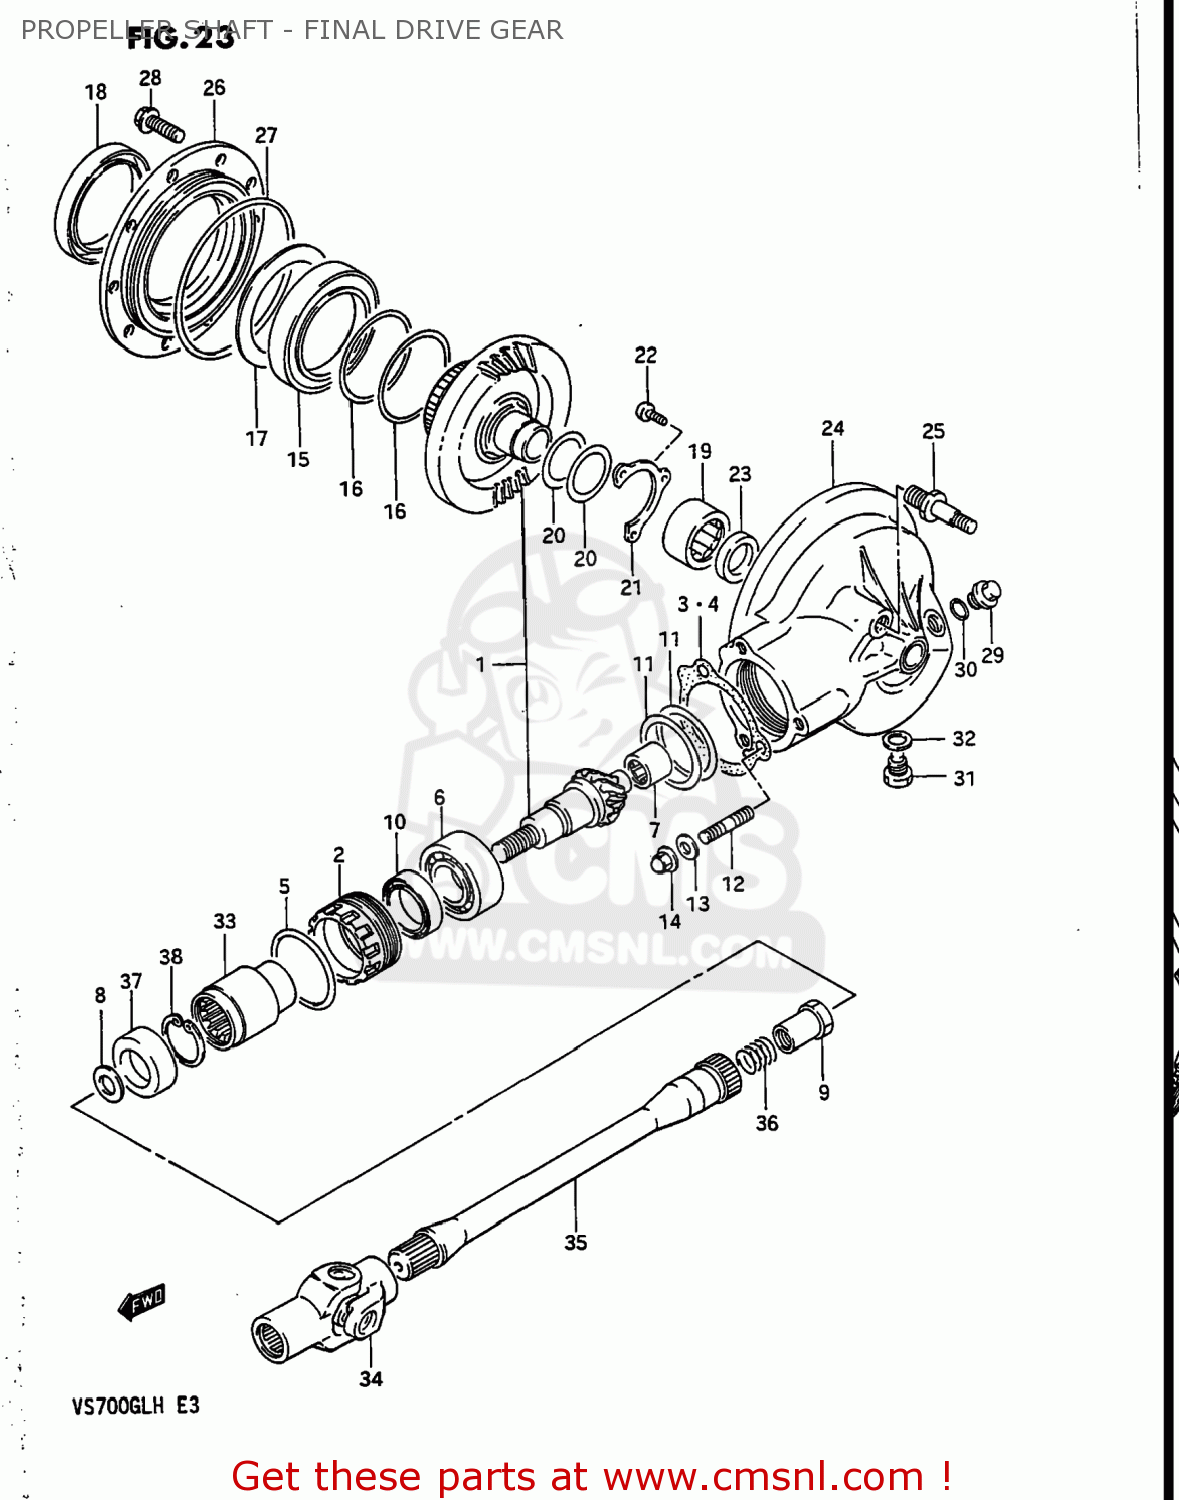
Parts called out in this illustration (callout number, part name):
1	GEAR & CASE SET,FINAL BEVEL
2	STOPPER,FINAL DRIVE BEARING
3	PLATE,BEARING STOPPER
4	PLATE,BEARING STOPPER
5	O RING(D:1.9,ID:61.6)
6	BEARING(30X62X23.8)
7	BEARING(17X32X16)
8	WASHER(16X29X4)
9	NUT
10	SEAL,OIL(38X54X6)
11	SHIM,FINAL DRIVE GEAR
12	STUD 10X25
13	WASHER
14	NUT
15	BEARING(70X110X13)
16	SHIM,DRIVEN GEAR BEARING T0.35
17	PLATE,FINAL DRIVEN BRG OIL
18	SEAL,OIL(70X96X16)
19	BEARING(32X46X17.7)
20	SHIM,FINAL DRIVEN GEAR
21	RETAINER,FINAL DRIVEN GEAR BRG
22	SCREW 6X12
23	SEAL,OIL(30X42X7)
24	CASE,FINAL GEAR
25	BOLT,STUD
26	CASE,FINAL GEAR BEARING
27	O RING(D:3.5,ID:131.6)
28	BOLT
29	PLUG
30	O RING(D:2.4,ID:17.8)
31	PLUG
32	GASKET(14X19.2X2) (NAS)
33	COUPLING,FINAL DRIVE GEAR
34	YOKE COMP,UNIVERSAL JOINT
35	SHAFT,PROPELLER
36	SPRING
37	SEAL,OIL(28.4X48X15)
38	CIRCLIP
